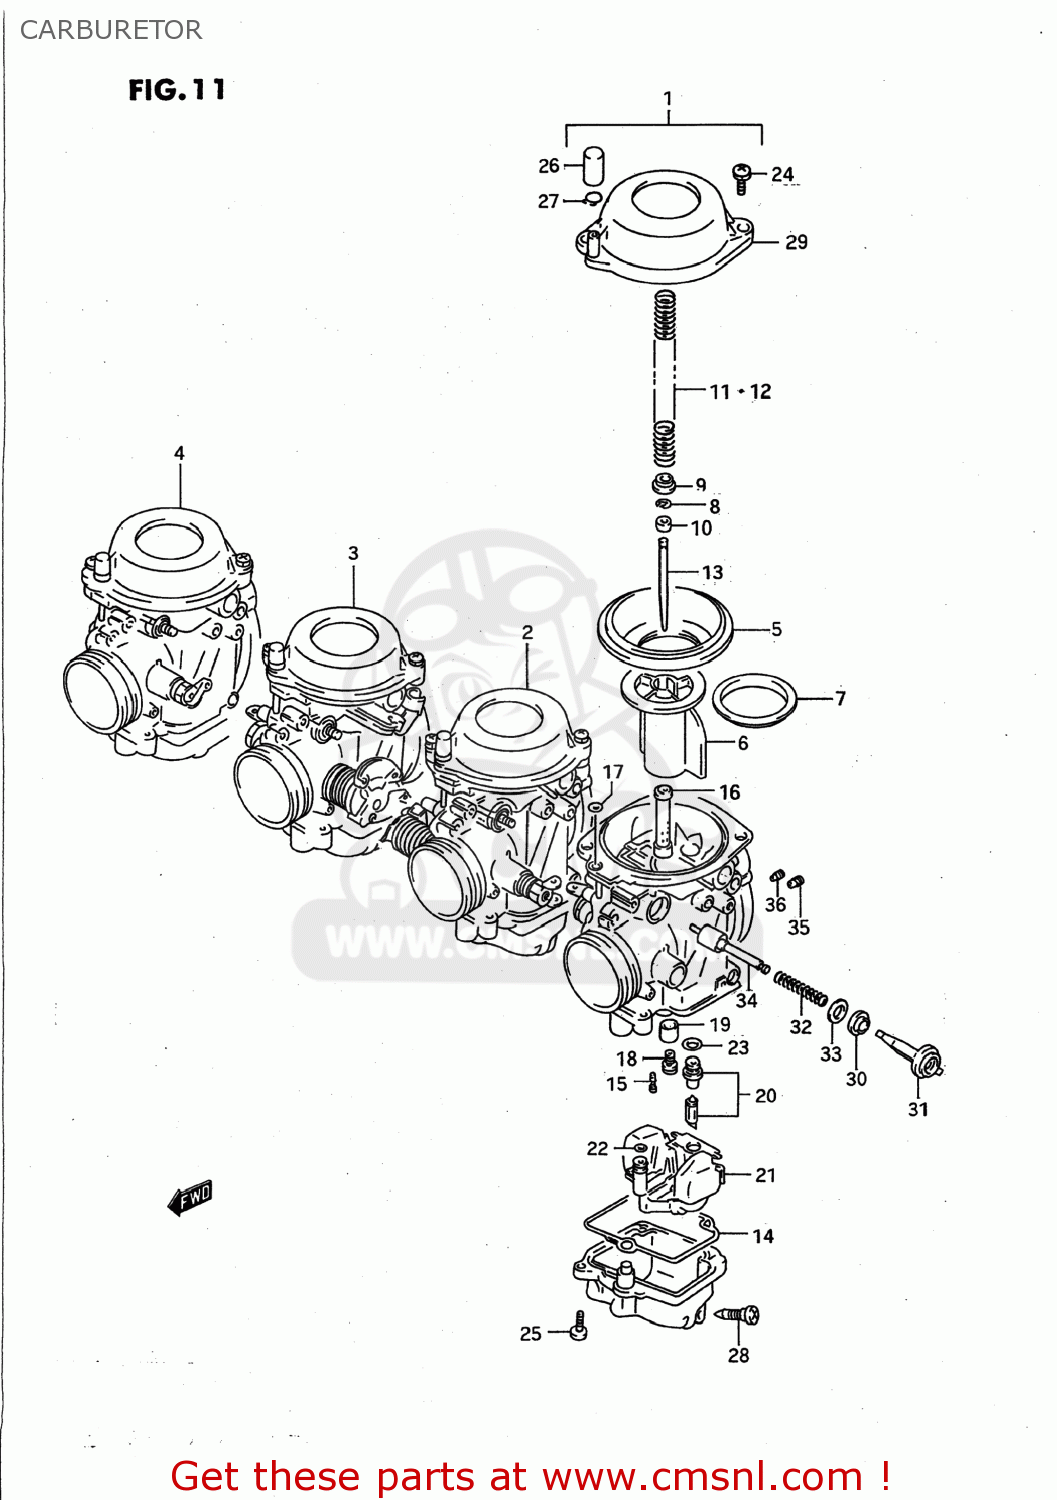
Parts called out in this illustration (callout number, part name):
1	CARBURETOR ASSEMBLY,LEFT
2	CARBURETOR ASSEMBLY,MIDDLE,LEFT
3	CARBURETOR ASSEMBLY,MIDDLE,RIGHT
4	CARBURETOR ASSEMBLY,RIGHT
5	DIAPHRAGM
6	VALVE,PISTON
7	RING
8	CLIP
9	RING
10	RING
11	SPRING
12	SPRING
13	NEEDLE JET
14	GASKET,FLOAT CHAMBER (NAS)
15	JET,PILOT(35)
16	JET,NEEDLE
17	O RING
18	JET,MAIN(115)
19	RING
20	VALVE ASSEMBLY,NEEDLE
21	FLOAT ASSY
22	O RING
23	O-RING,NEEDLE VALVE
24	SCREW
25	SCREW
26	CAP
27	CLIP
28	SCREW,DRAIN
29	COVER,DIAPHRAGM
30	CAP,STARTER
31	HOLDER,GUIDE
32	SPRING
33	WASHER
34	PLUNGER ASSY
35	JET,AIR(0.5)
36	JET,AIR(1.25)
